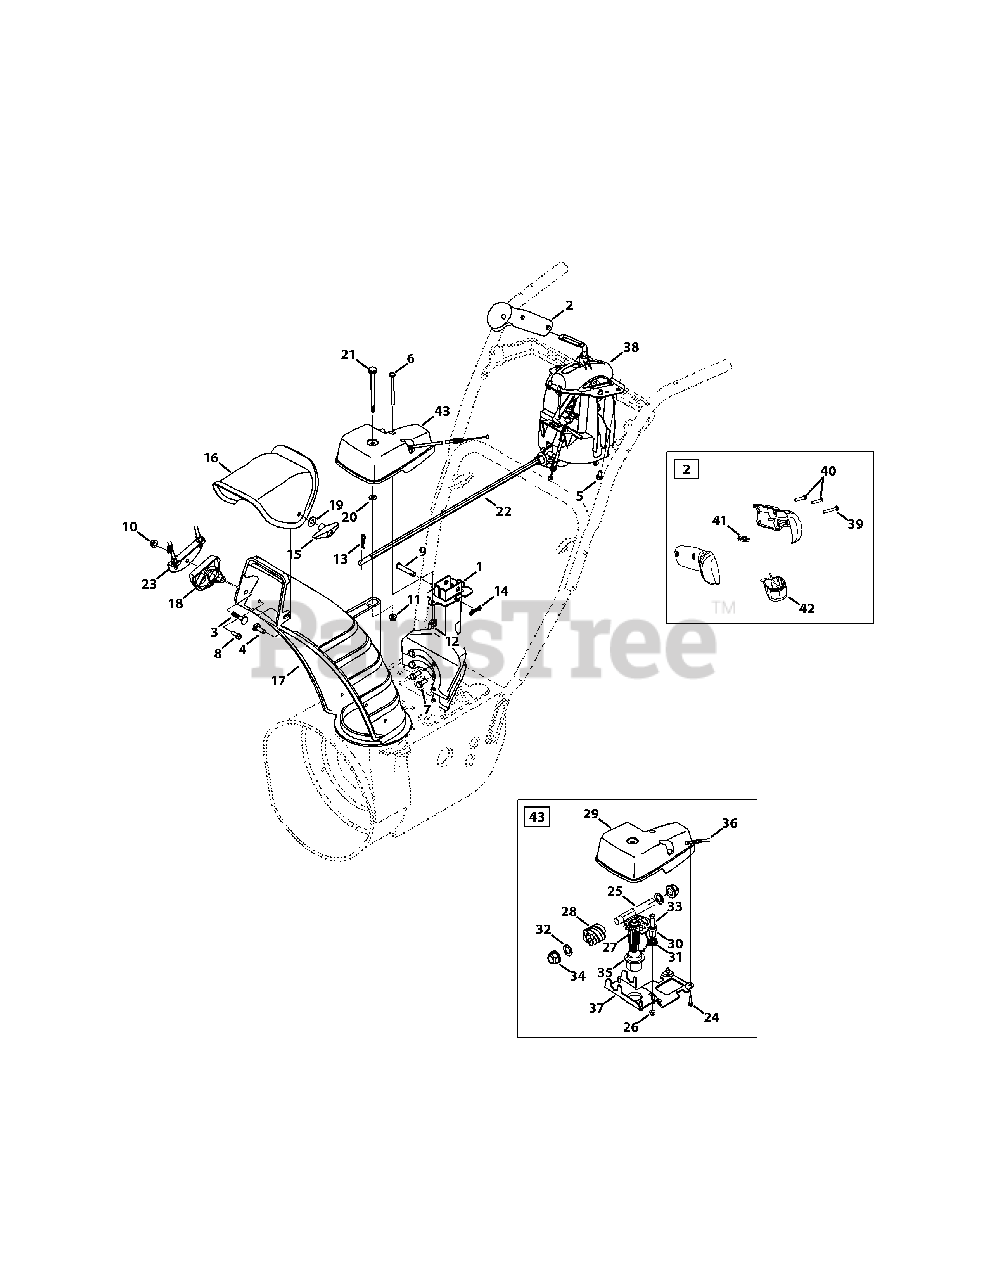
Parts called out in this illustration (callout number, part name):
1	Chute Support Bracket (large Block engine)
1	Chute Support Bracket (small block engine)
2	Trigger housing
3	Bolt, Carriage, 5/16-18 x 1.50 4-Way
3	Bolt, Carriage, 5/16-18 x .750 2-Way
4	Bolt, Carrier, 5/16-18 x 1.00
5	Screw, Hi-Lo, 1/4-15 x 0.50
6	Hex Head Screw, 1/4-20 x 3.00
7	Hex Head Screw, 5/16-24 x .750
8	Screw, Hi-Lo, 1/4-15 x 0.750
9	Clevis Pin, 3/8 x 1.87
10	Nut, Flange Lock, 5/16-18
11	Nut, Flange Lock, 1/4-20
12	Wing Nut, 1/4-20
13	Internal Cotter Pin
14	Bow-Tie Cotter Pin
15	Star Knob, 5/16-18
16	Chute, Upper 4-Way
16	Chute, Upper 2-Way
17	Chute, Lower
18	Cable Guide, Chute Tilt
19	Washer, Flat, .349 x .879
20	Washer, Flat, .25 x .630
21	Screw, Shoulder, .312 x 3.5 x 1/4-20
22	Chute Rod, 3/8 Hex
24	Screw, 12-16 x .75
25	Hex Shaft
26	Hexlock Nut, 1/4-28
27	Gear, 14 T
28	Worm
29	Gear Cover
30	Pawl Lock
31	Torsion Spring, .721 ID x .474
32	Washer, Flat, .625 x 1.0 x .067
33	Screw, Shoulder, .34 x .95 x 1/4-28
34	Hex Bearing
35	Flange Bearing
36	Cable Lock
37	Gear Bracket
38	Chute Control, 4-Way
38	Chute Control, 2-Way
38	Chute Control Housing, 4-Way, assembly
38	Chute Control Housing, 2-Way, assembly
38	Gear set
39	Screw, #8 x 1.00
40	Screw, 8-32 x .750
41	Joystick Plug
42	Joystick Trigger
43	Chute Rotation Gearbox
